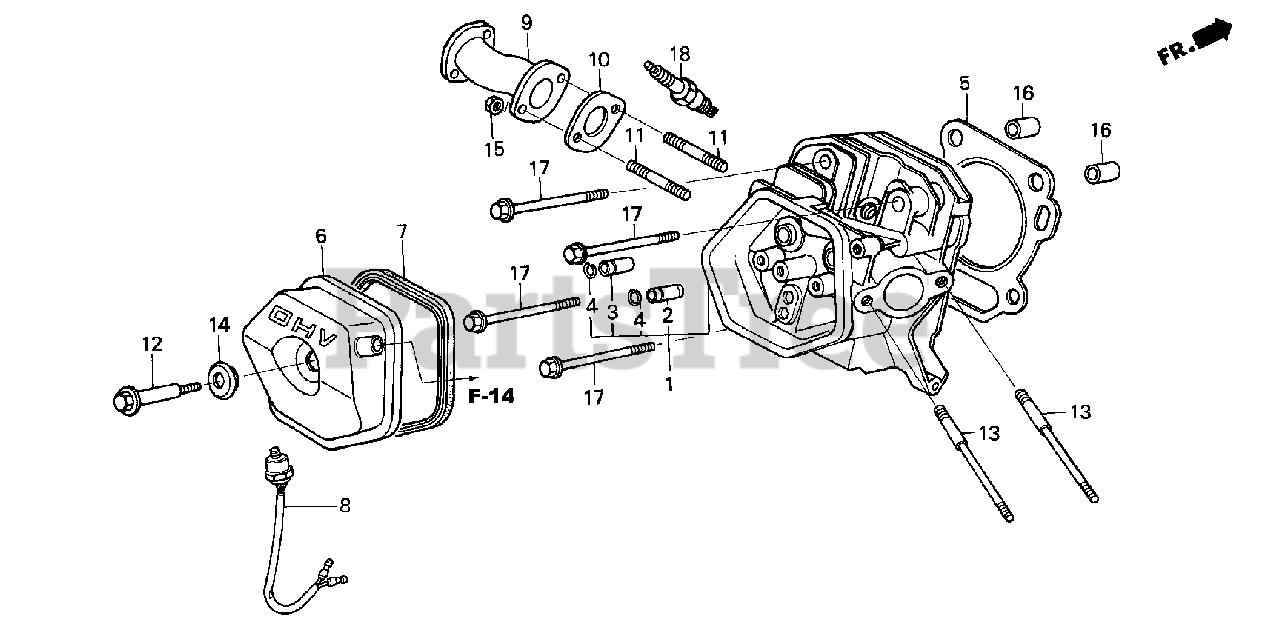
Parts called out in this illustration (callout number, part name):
1	CYLINDER HEAD
2	GUIDE, VALVE (OS)
3	GUIDE, EX. VALVE (OS)
4	CLIP, VALVE GUIDE
5	GASKET, CYLINDER HEAD
6	COVER KIT, HEAD
7	GASKET, CYLINDER HEAD COVER
7	GASKET, HEAD COVER
8	SWITCH, THERMO
10	GASKET, EX. PIPE
11	BOLT, STUD (8X34)
12	BOLT, HEAD COVER
13	BOLT, STUD (8X111)
14	WASHER, HEAD COVER
15	NUT, HEX. (8MM)
16	PIN, DOWEL (12X20)
17	BOLT, FLANGE (10X80)
18	SPARK PLUG (BPR5ES-11) (NGK)
18	SPARK PLUG (W16EPR-U11) (DENSO)
18	SPARK PLUG (BPR5ES) (NGK)
18	SPARK PLUG (W16EPR-U) (DENSO)
